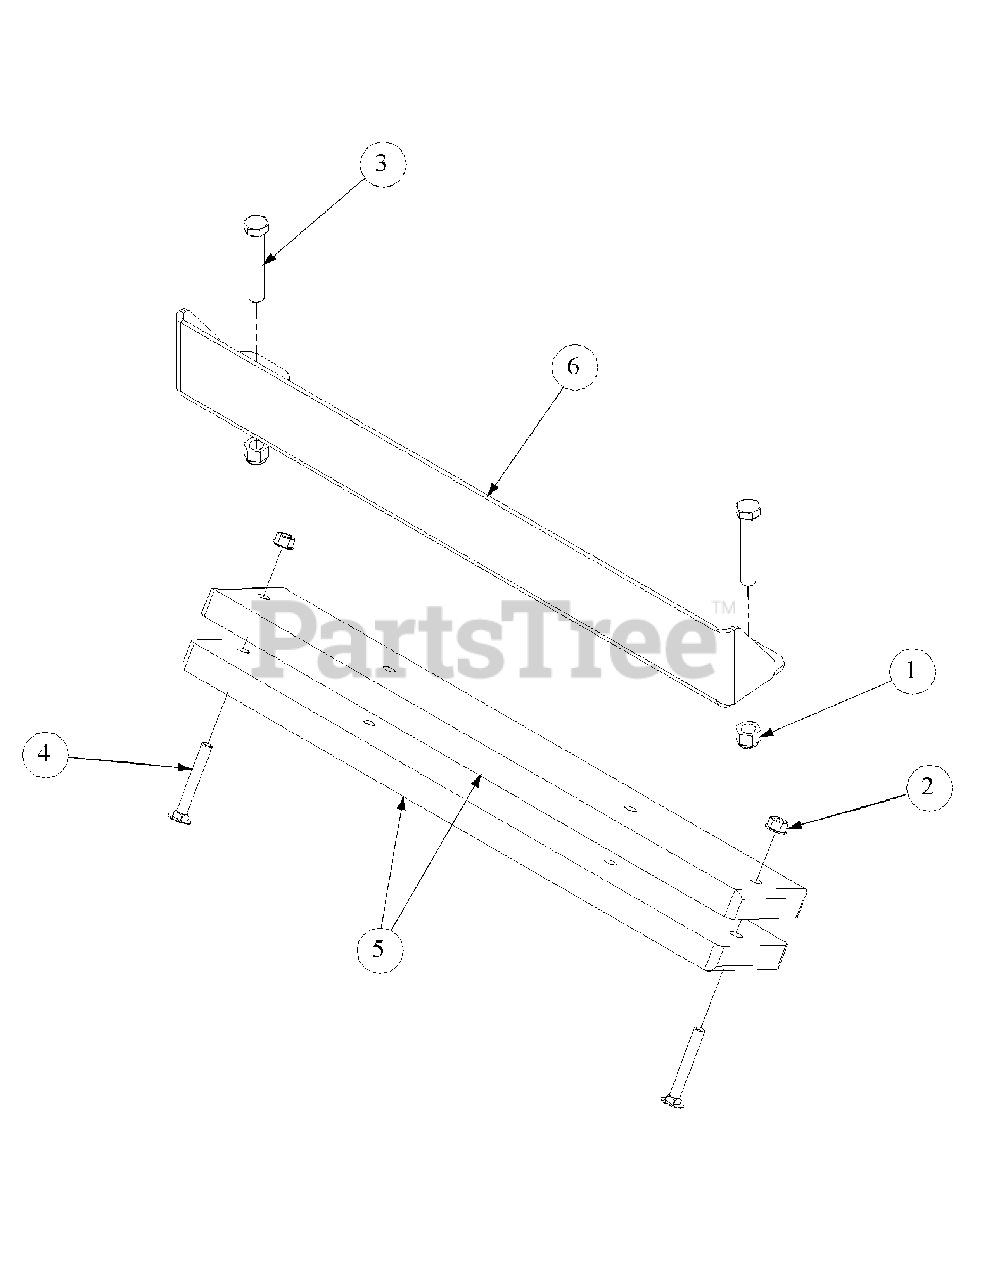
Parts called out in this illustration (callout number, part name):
1	Hex Nut, 1/2-13, Insert Lock
2	Nut, Hex 3/8-16 Flange Lock
3	HHCS, 1/2-13, 3.00
4	Carriage Bolt, 3/8-16 x 2.75
5	Bar, Weight
6	Rear Bumper Plate
